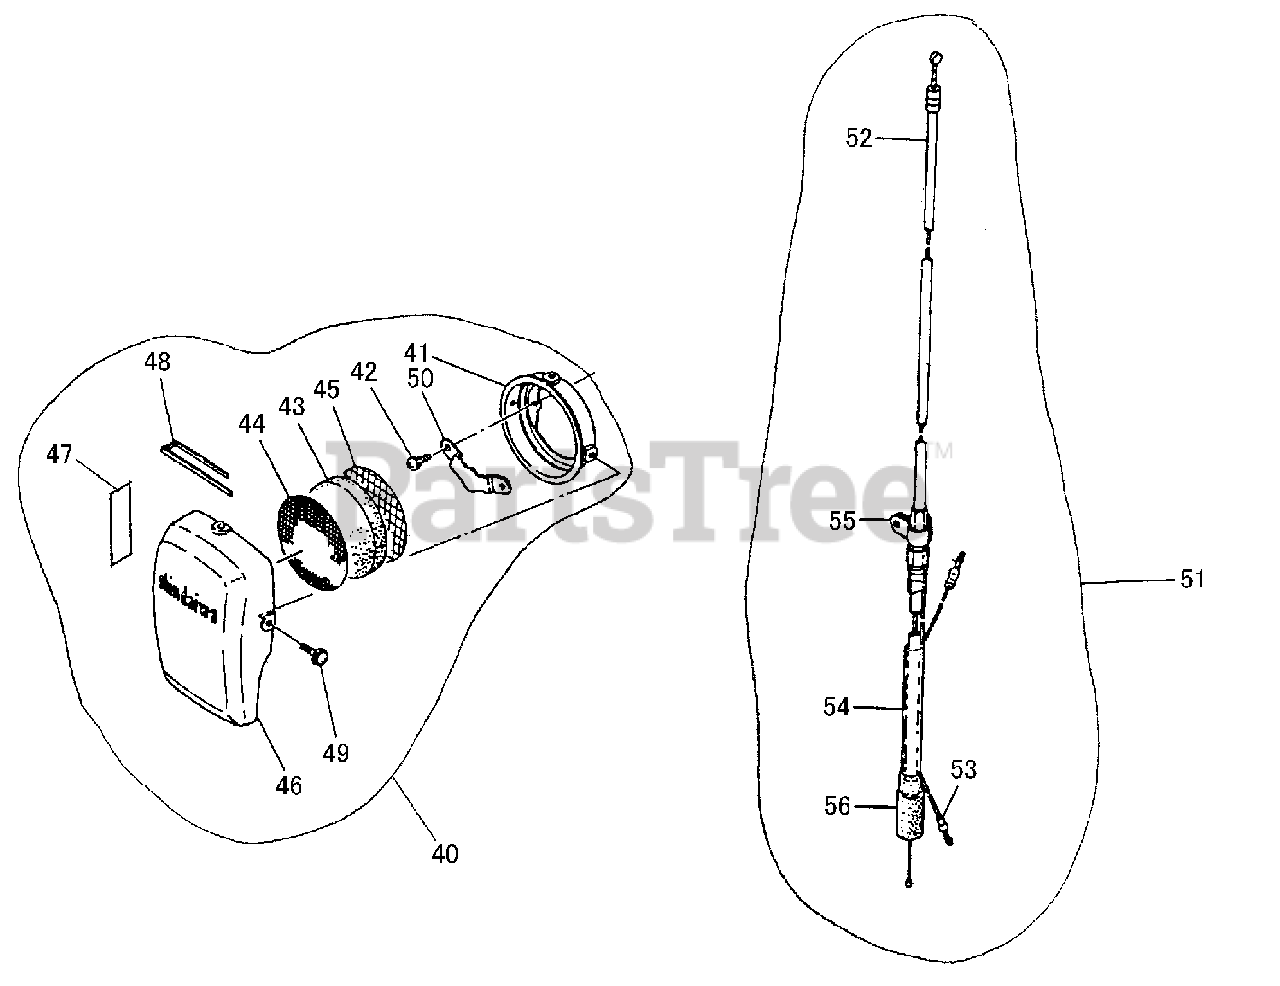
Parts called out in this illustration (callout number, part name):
40	AIR CLEANER KIT
41	CASE, AIR FILTER
42	SCREW
43	FILTER, AIR - FOAM
44	SCREEN - OUTER
45	SCREEN - INNER
46	COVER, AIR FILTER
47	LABEL - CHOKE
48	CLIP
49	SCREW
51	CONTROL CABLE ASSY
52	CABLE, THROTTLE
53	LEAD
54	PIPE
55	CLAMP, CABLE
56	CAP, DUST
